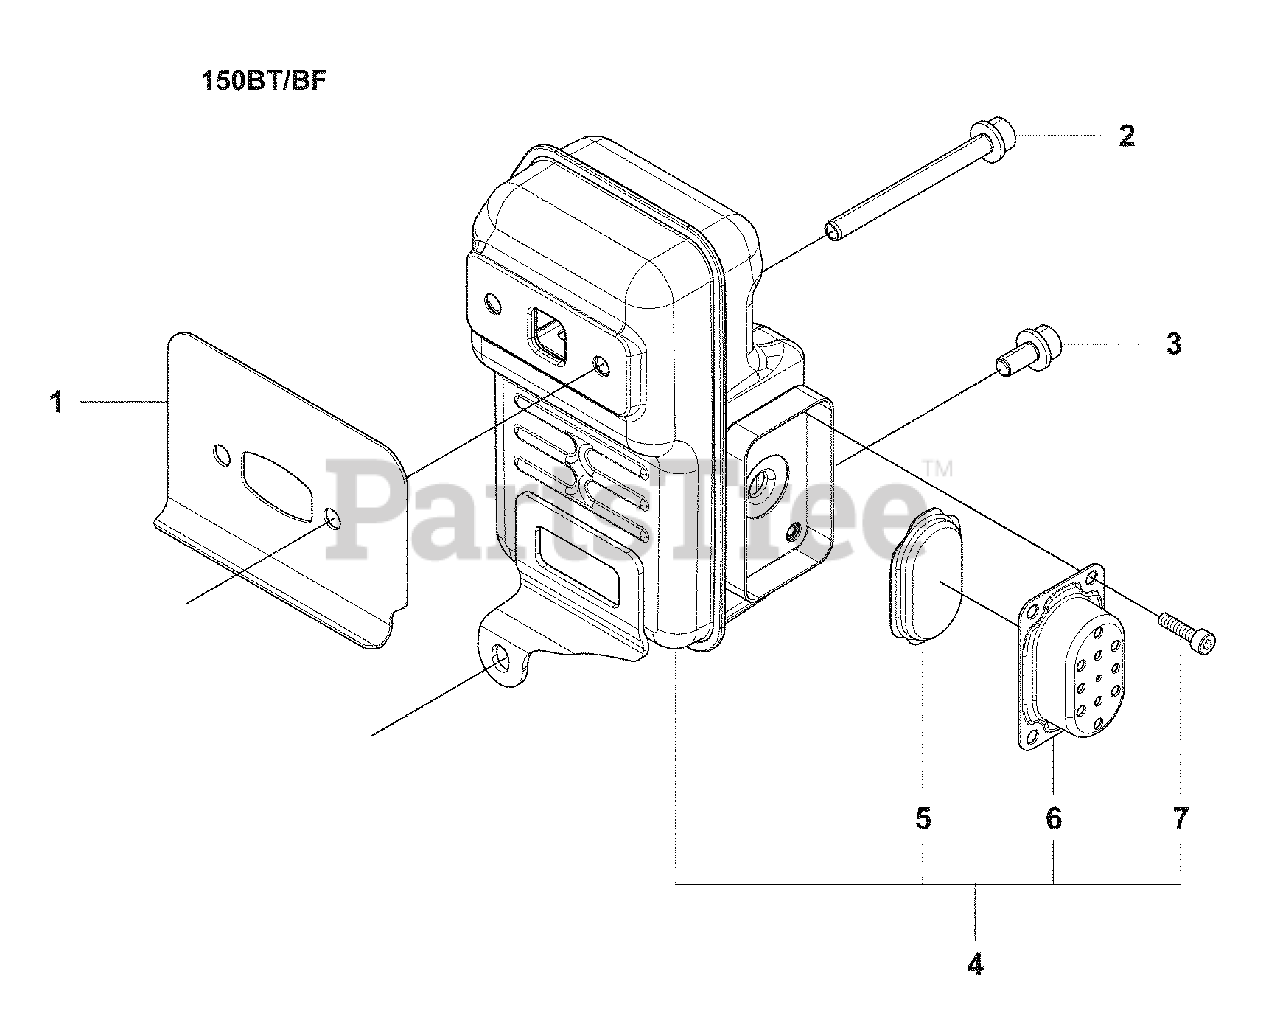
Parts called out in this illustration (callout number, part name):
1	Gasket
3	Bolt
4	Muffler Assembly
5	Spark Arrestor Screen
6	Exhaust Duct
